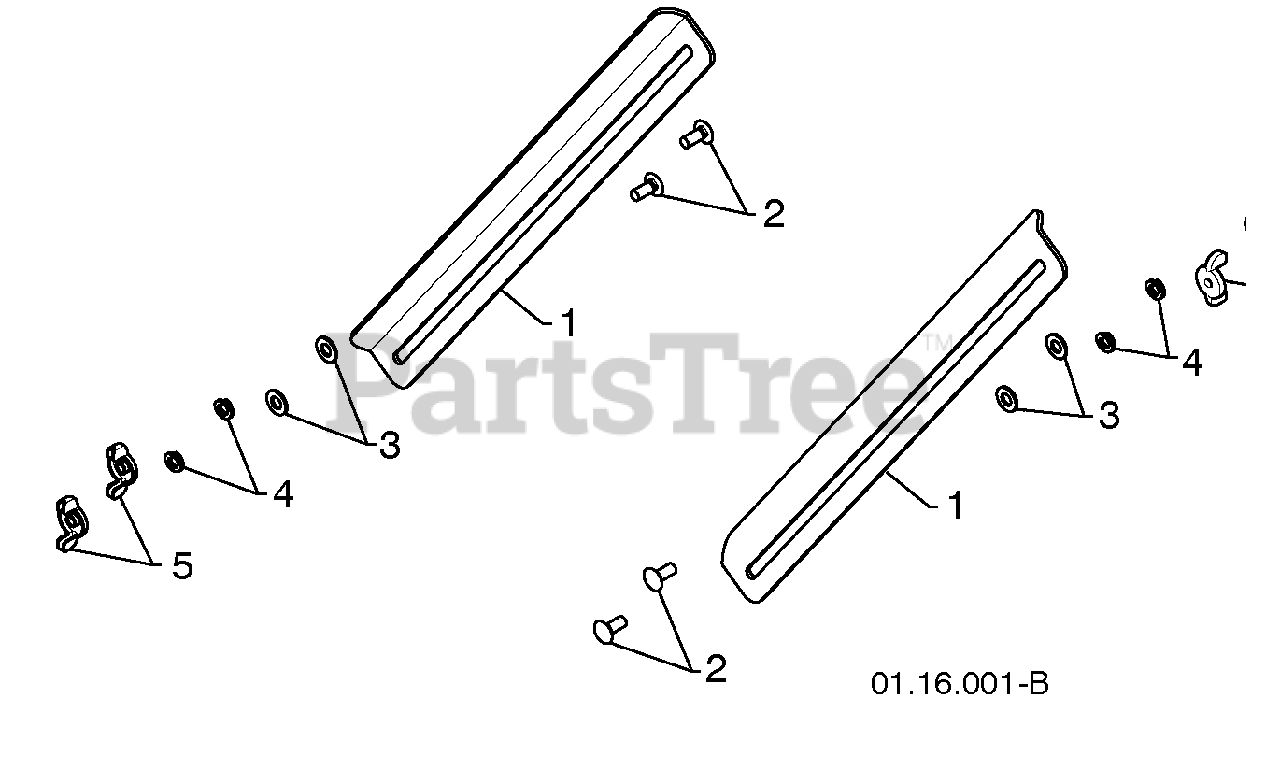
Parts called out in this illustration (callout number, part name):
1	DRIFT CUTTER BAR
2	CARRIAGE BOLT 5/16-18 X .750
3	PLASTIC WASHER
4	LOCKWASHER 5/16
5	NUT 5/16-18
